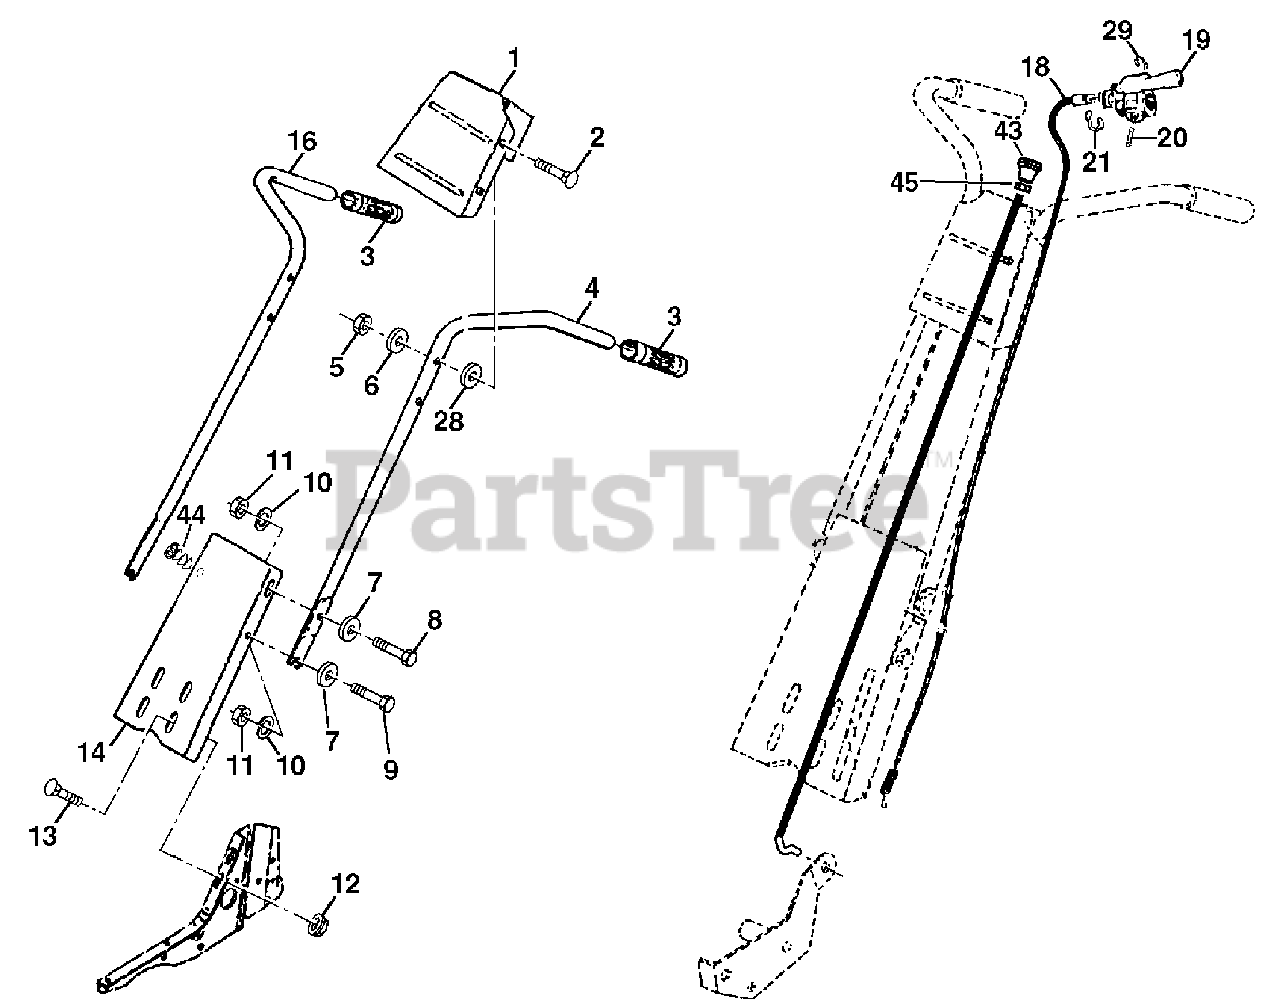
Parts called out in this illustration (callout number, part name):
1	Panel Pnt Control
2	Bolt, Carriage 5/16-18 UNC x 1-1/2
3	Grip, Handle
4	Handle, L.H.
5	Locknut, Crown 5/16-18
6	Washer 11/32 x 11/16 x 16 Ga.
7	Washer 3/8 x 7/8 x 14 Ga.
8	Bolt, Hex Hd. 5/16-18 x 1
9	Bolt, Hex Hd 5/16-18 x 3/4
10	Washer, Lock 5/16
11	Nut, Hex 5/16-18
12	Nut, Flanged 50/16-18
13	Bolt, Carriage 5/16-18 x 3/4 Gr. 5
14	Panel, Handle
16	Handle, R.H.
18	Cable, Control, Tine
19	Lever, Control, Tine
20	Pin, Pivot
21	Ring, Klip
28	Washer 13/32 x 13/16 x 12 Ga.
29	Retaining, Ring
43	Cable Assembly, Reverse
44	Clip
45	Nut, Hex Keps 3/8-16
